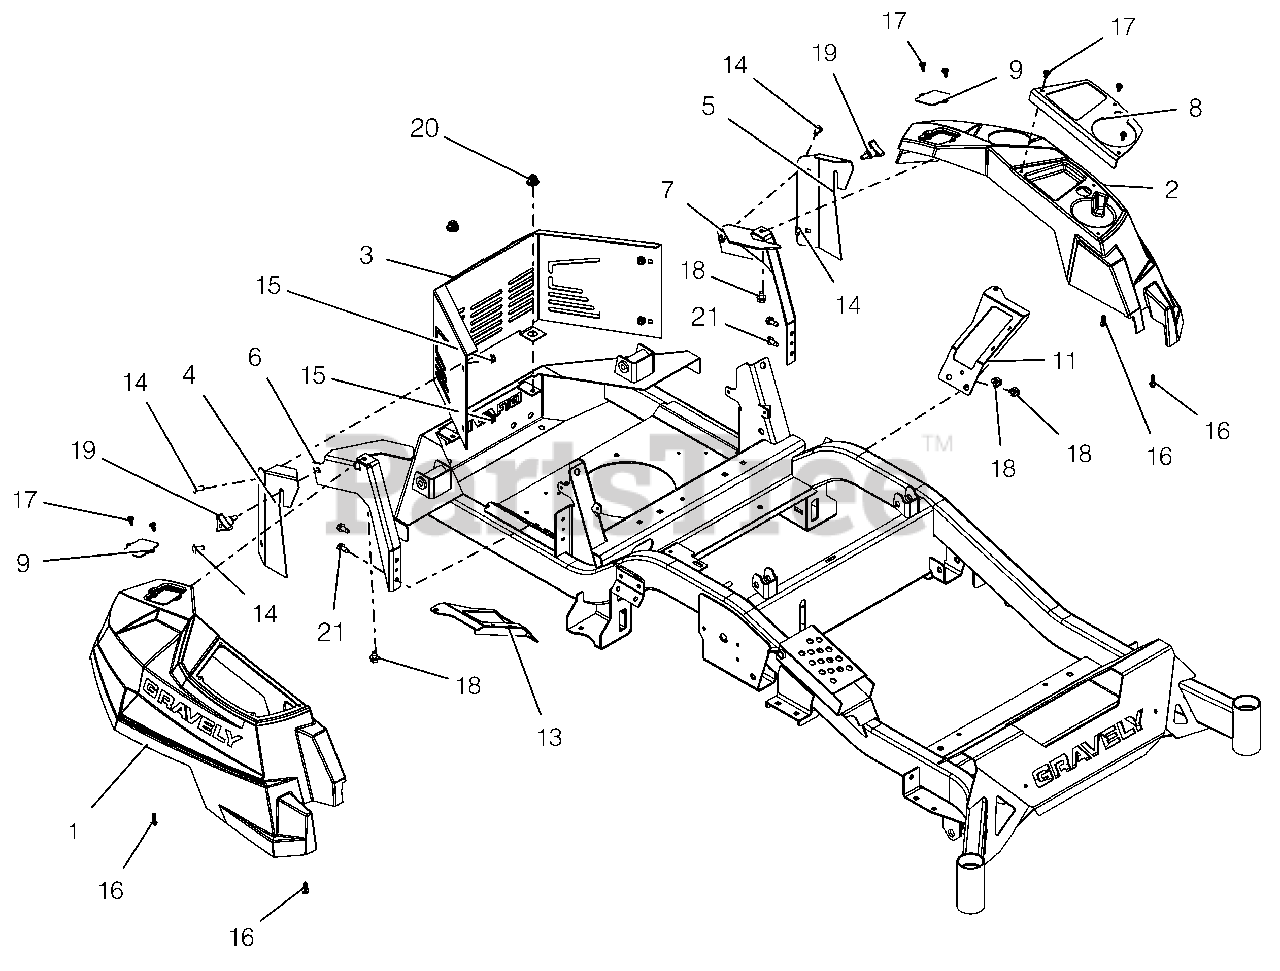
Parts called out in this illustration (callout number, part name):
1	FENDER, RH HD (2017)
2	FENDER, LH HD (2017)
3	GUARD, HD ENGINE
4	TRIM, HOOD STYLE (RIGHT)
5	TRIM, HOOD STYLE (LEFT)
6	BRKT, RH FENDER MTG
7	BRKT, LH FENDER MTG
8	PANEL, HD
9	PLATE, ROPS HOLE-HD
11	WLDMT, LH FENDER MOUNT
13	WLDMT, RH FENDER MOUNT
14	@BLT-RHDSSQNK .31-18X.75 G5YZ
15	@NUT-LK-CTR-FLG .31-18 YZ GR F
16	SCR-PLASTITE .25-10X.75, YWZC
17	SCR-PAN .25-15X.50 6L H/LZB500
18	@SCR-TAP .38-16X.50 HWH TR YWZ
19	KNOB,WING STUD 5/16-18 X .75
20	GROMMET, 10MM BOLLHOFF
21	@SCR-TAP .31-18X.75 HWH TR YWZ
